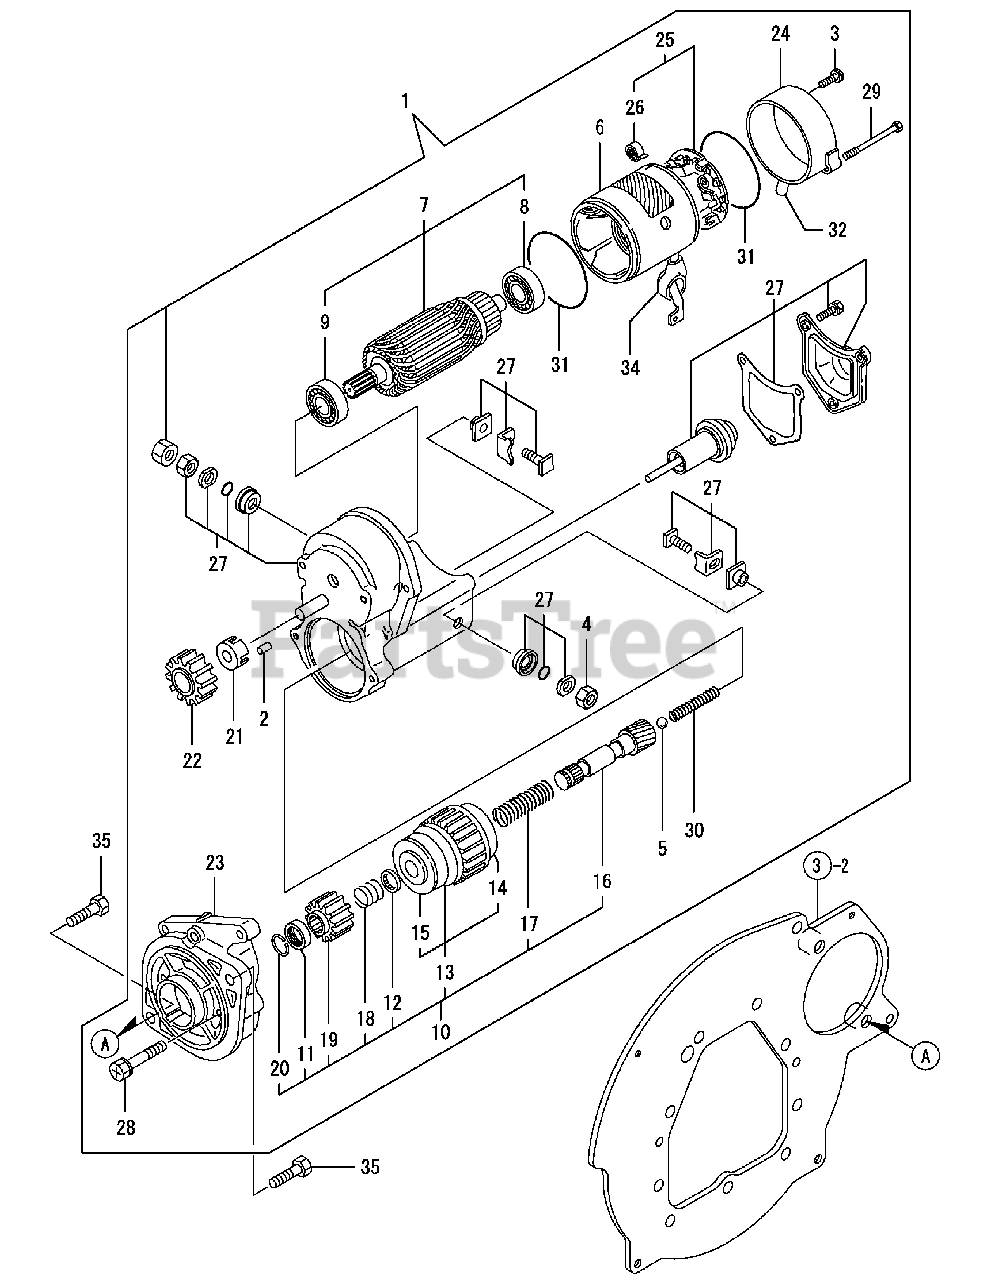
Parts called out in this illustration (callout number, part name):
10	CLUTCH SUB-ASSY
13	CLUTCH ASSY, STARTER
35	BOLT M12X 30 PLATED
